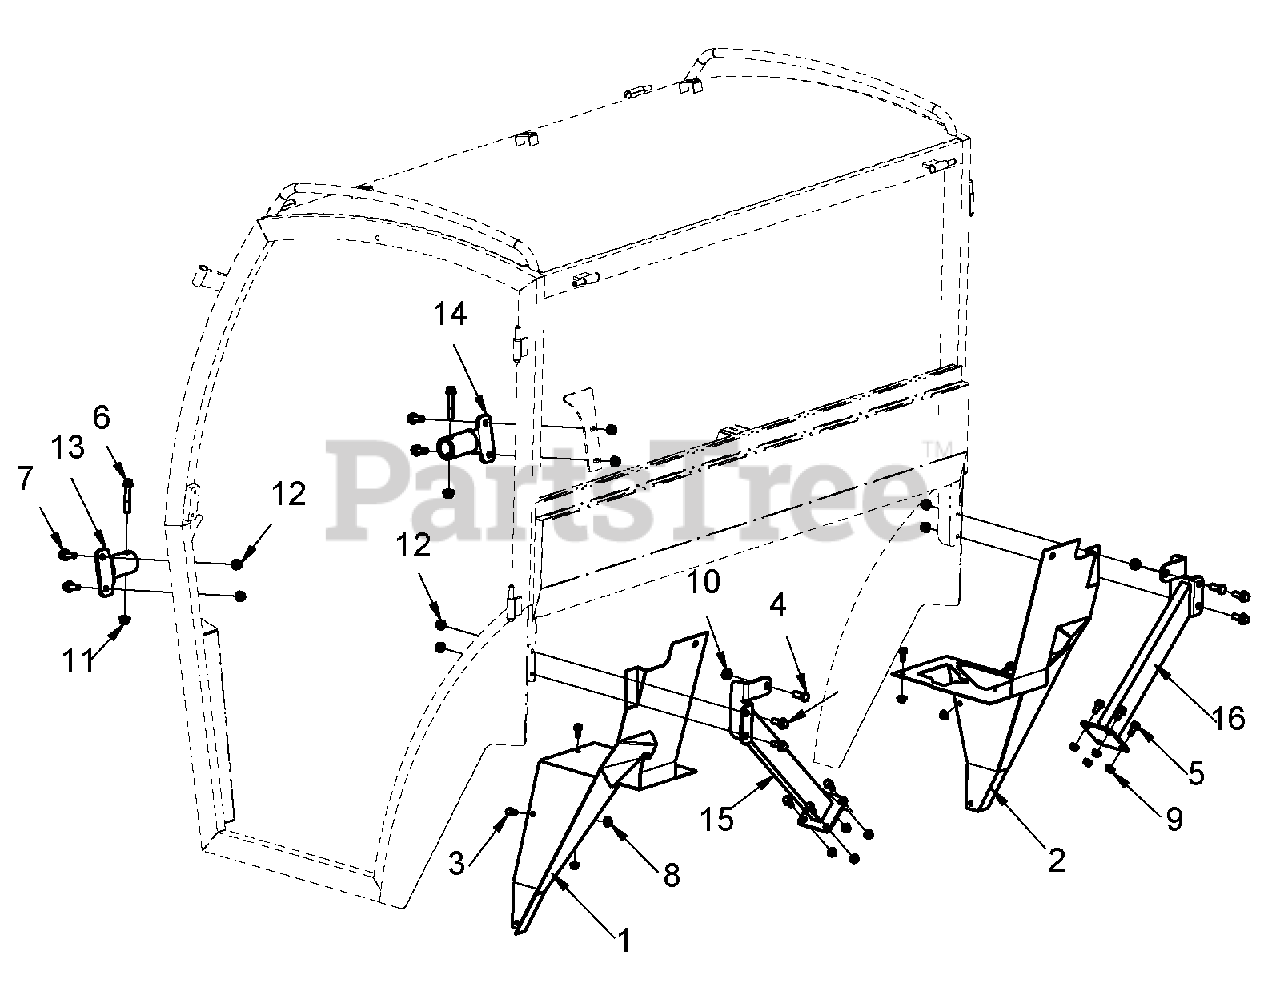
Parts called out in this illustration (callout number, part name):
1	Filler Panel LH
2	Filler Panel RH
3	Bolt, Serrated Hex Flange Washer Head .25-20 x .75
4	Bolt, Hex .44-14 x 1.00 Grade 5
5	Bolt, Serrated Hex Flange Washer Head .312-18 x .75
6	HFS M10 x 1.5 x 60 GR10.9
7	Bolt, Serrated Hex Flange Washer Head .375-16 x 1.0
8	Nut, .25-20 Nyloc Flange
9	Nut, .31-18 Nyloc Flange
10	Nut, Nyloc Flange .44-14
11	Locknut, M10 x 1.50 Whiz
12	Nut, .38-16 Nyloc Flange
13	Bracket, Left Front
14	Bracket, Right Front
15	Bracket, Left Rear
16	Bracket, Right Rear
